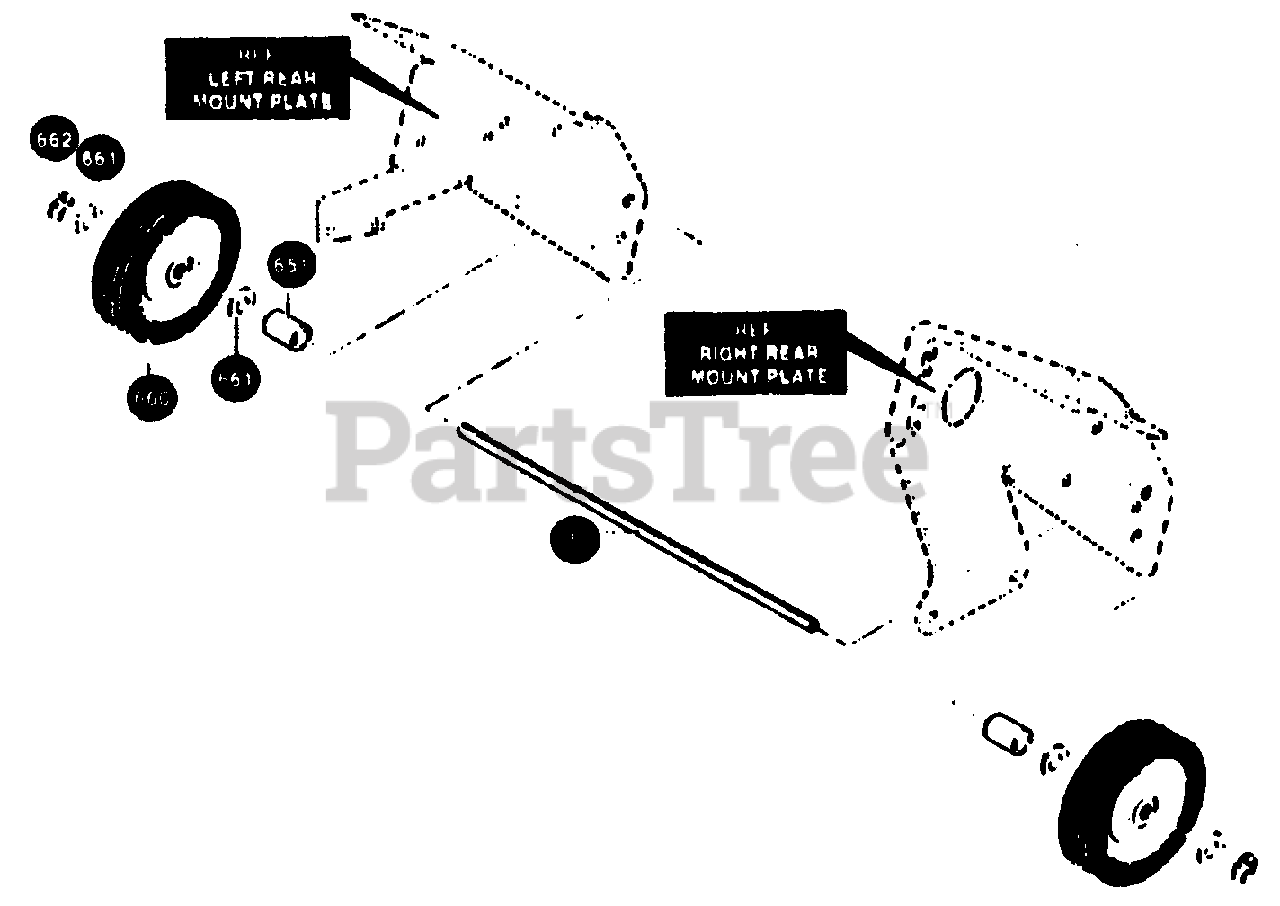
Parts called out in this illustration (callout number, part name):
650	SHAFT, AXLE
651	SPACER, SLEEVE
652	WASHER, FLAT .406X .81X .065
660	TIRE & RIM
661	WASHER, FLAT .406X.81X.065
662	RING, RET E
